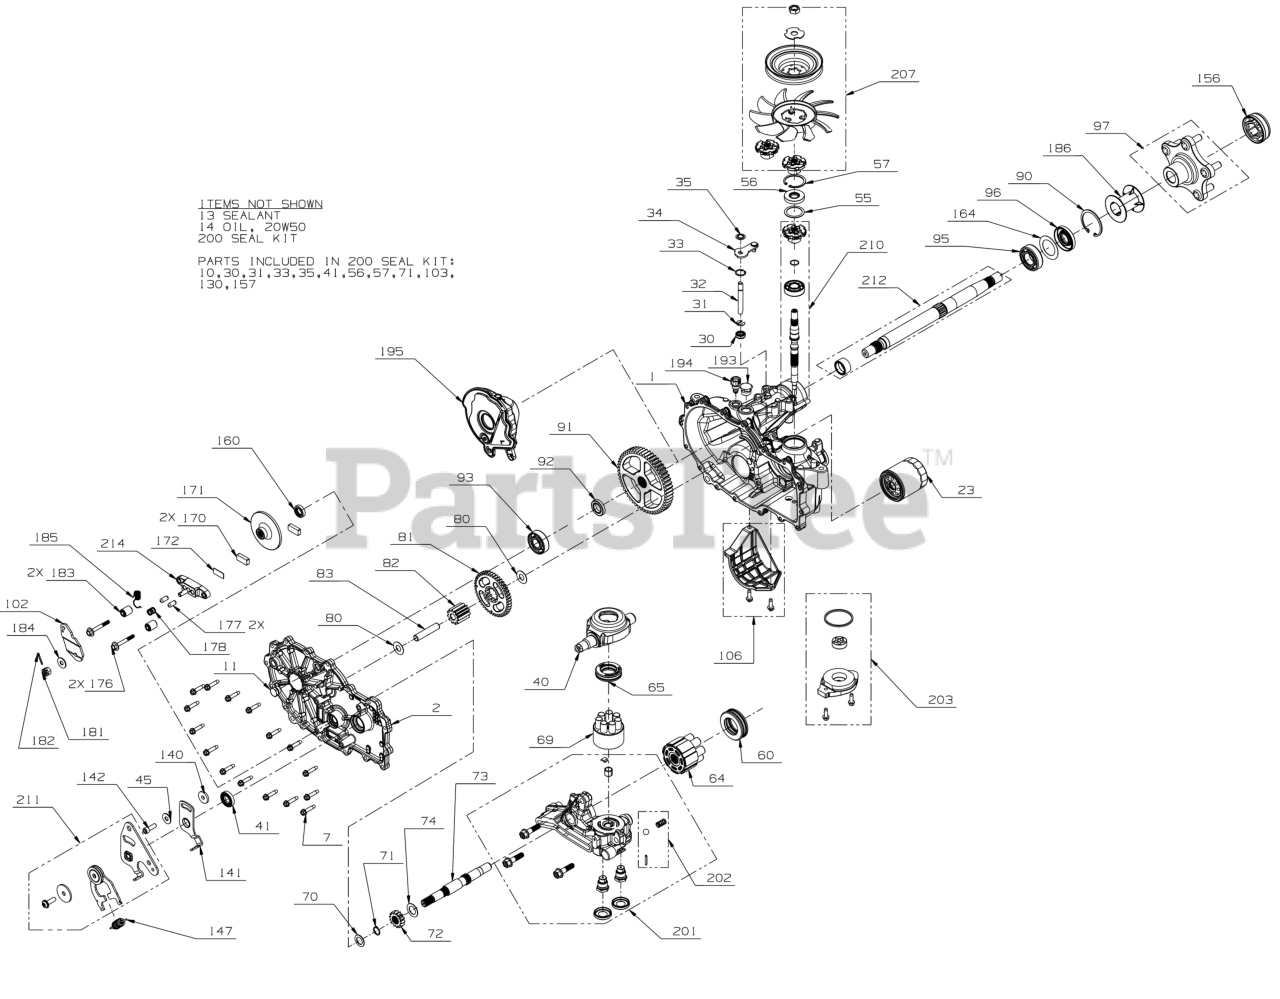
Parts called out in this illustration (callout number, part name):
1	MAIN HOUSING KIT (LH)
2	SIDE COVER KIT (LH)
7	SCREW-WASHER HEAD
11	VENT PLUG
13	SEALANT-HOUSING
23	OIL FILTER
30	SEAL-LIP .375 X .75 X .25
31	RETAINING RING
32	BYPASS RODS
33	RETAINING RING
34	ARM-BYPASS
35	RETAINING RING
40	SWASHPLATE-TRUNNION
45	FLAT WASHER
55	WASHER 1.23X1.56X
57	RETAINING RING
60	THRUST BEARING
64	CYLINDER BLOCK ASSEMBLY
65	THRUST BEARING
69	BLOCK KIT-7 PISTON
70	FLAT WASHER
71	RETAINING RING
73	MOTOR SHAFT
74	MOTOR SHAFT WASHER
81	GEAR-45T JACK SHAF
82	GEAR-11 T
83	PIN-JACKSHAFT
90	RETAINING RING
91	GEAR-54 T
92	SPACER .75X1.32X.257
93	BALL BEARING
95	BALL BEARING
97	5 BOLT HUB KIT
102	ARM-BRAKE
106	FILTER GUARD KIT
140	SPACER .32 x 1.005 x .179
141	ARM-NEUTRAL (RH)
142	SCREWS KIT-RTN
147	EXTENSION SPRING
156	COVER-NUT
170	BRAKE PUCK
171	ROTOR-BRAKE
172	PUCK PLATE
176	BOLT-SPECIAL FLANG
177	ACTUATING PIN
178	BRAKE SPRING
182	COTTER PIN-3/32 DIA x .75
184	FLAT WASHER
185	EXTENSION SPRING (LH)
186	TUBE-AXLE 2.03
193	PLUG 3/4-16
194	BREATHER FITTING 9/16-18
195	EXPANSION TANK (LH)
201	CENTER SECTION KIT (LH)
202	KIT-CHARGE RELIEF
203	CHARGE KIT
207	FAN & PULLEY KIT
209	PULLER KIT-HUB
210	INPUT SHAFT KIT
211	RETURN KIT-NEUTRAL (RH) ZT2800 RZT
212	SHAFT KIT-AXLE
214	BRAKE YOKE ASSEMBLY
